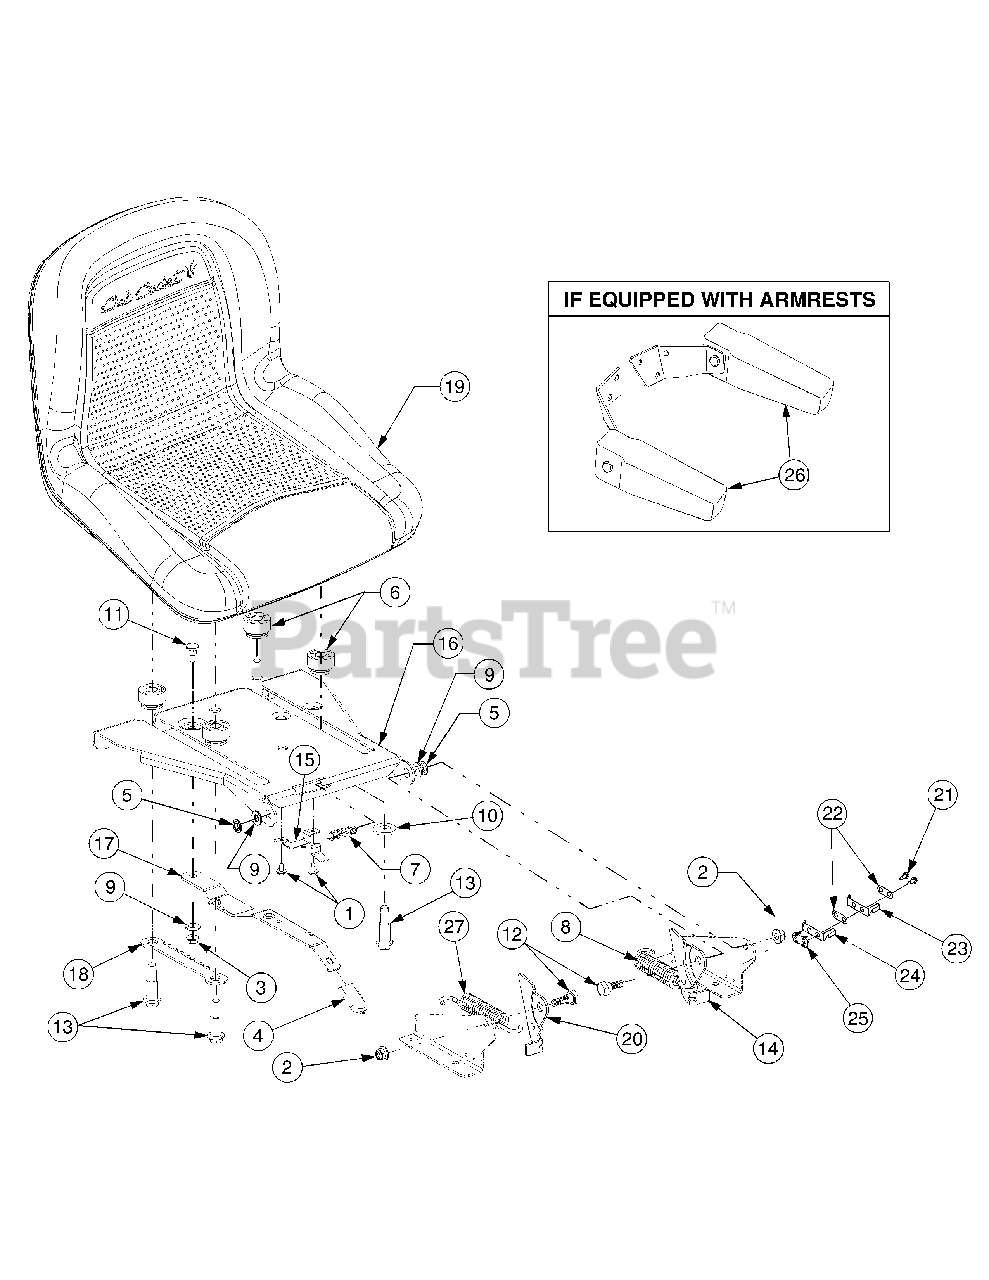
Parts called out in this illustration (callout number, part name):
1	Screw Hex Wash Hd., #10-16, 0.375
2	Nut, Flange Insert Lck, 5/16-18,Gr5
3	Nut, Flange Lock, 1/4-20
4	Grip, Seat Adjustment (Yellow)
5	Nut, Speed, .3125 ID
6	Spacer, Seat, Adjustment
7	Spring, Compression .41 OD x 1.5
8	Spring, Extension, .84 Dia x 4.6 Lg
9	Washer, Flat, .344 x .688 x .065
10	Washer, Flat, .531 x 1.062 x .134
11	Screw, Shoulder, .34 x .285, 1/4-20
12	Shoulder, Screw .437 x .286 Lg
13	Screw, Shoulder, .50 x.925:3/8-16
14	Bracket, Seat Lift
15	Stop, Seat, Adjustment
18	Selector, Seat, Adjustment
19	Seat, Mid-back, V-1480
19	Graphic, Made in USA
19	Graphic, Cub Cadet
20	Bracket, Seat Lift
21	Screw, #8-18 x.50
22	Plate, Insulator
23	Spring Switch, Outer
24	Spring Switch, Inner
25	Plate, Insulator Boss
26	Arm Rest (If Equipped)
27	Spring, Extension, .815 x 4.775
